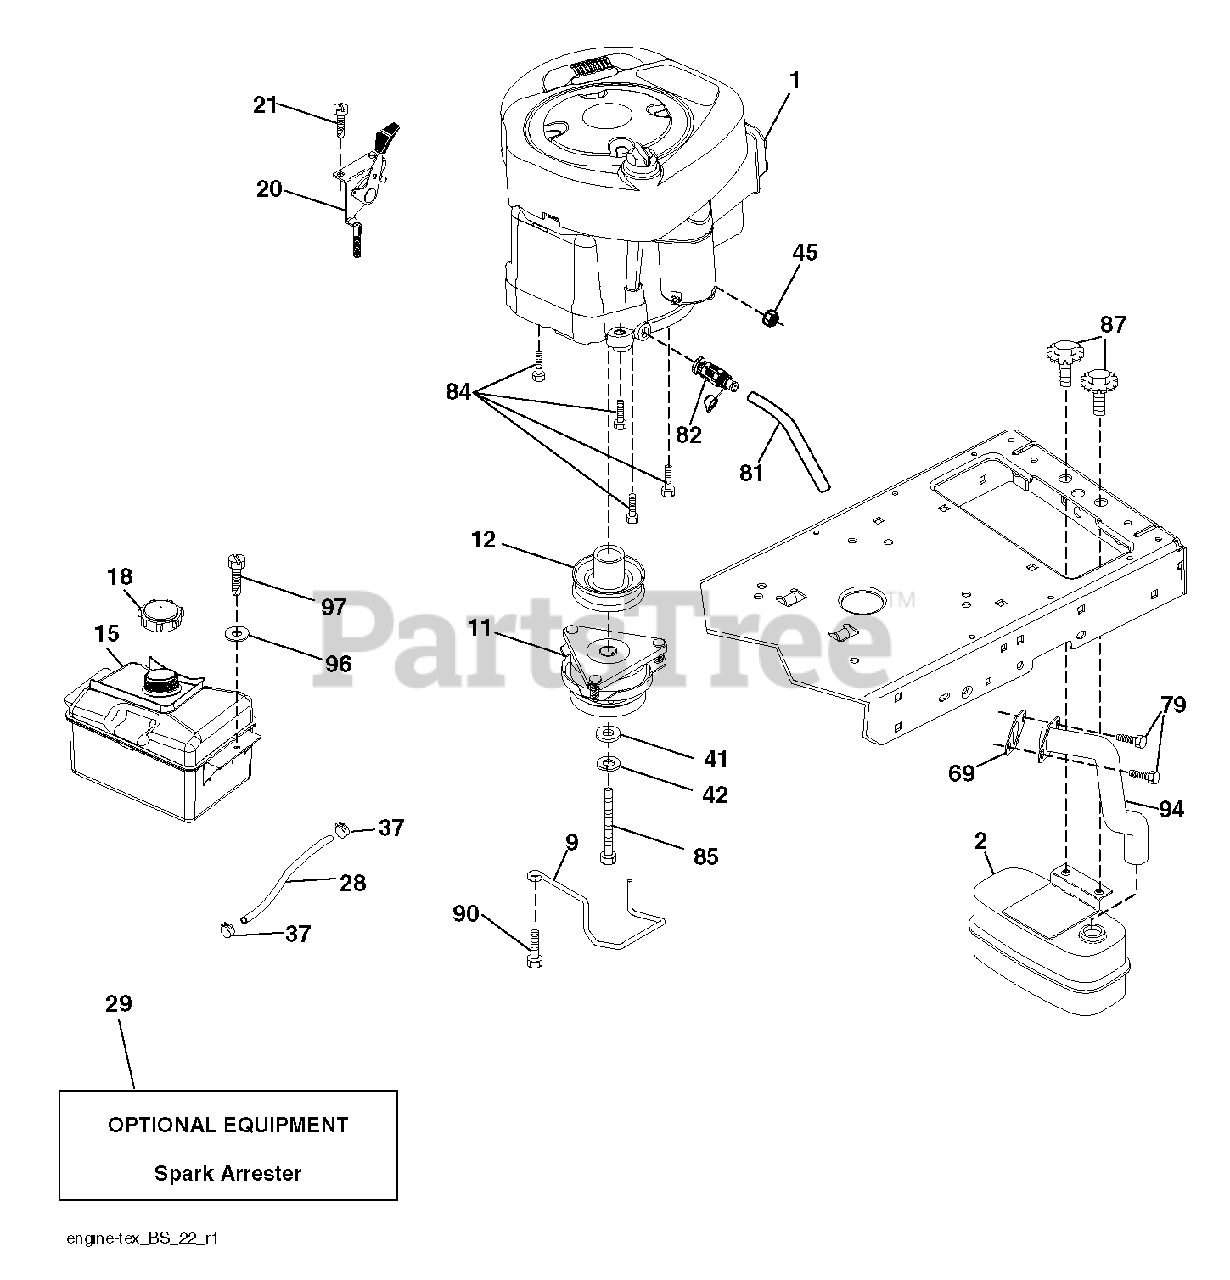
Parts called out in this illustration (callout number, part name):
2	MUFFLER.SINGLE.LRG.BRIGGS.KOHL
9	KEEPER BELT ENGINE
11	CLUTCH.ELECTRIC.LT.48"*
12	PULLEY.ENGINE.TUFFTORQ
15	FUEL.TANK.ASM.NON-EPA
18	CAP ASM.FUEL.2.25"FR.
20	CONTROL.TH/CK.C.
21	SCREW.#10 X 0.750.BOS
28	LINE.FUEL.20
29	KIT.SPARK ARRESTOR 794945 B&S
37	HOSE CLAMP
42	LOCKWASHER
45	NUT
69	REPL BY 532 27 22-93
79	SCREW.SOCKET HD.5/16-1
81	TUBE, DRAIN OIL ASM.
82	VALUE.OIL.DRAIN
84	SCREW.3/8-16
85	BOLT HEX 7/16-20X4-1/4"
87	BOLT, 5/16-18 X 1 3/4
90	SCREW 3/8-16X1
94	EXHAUST.TUBE.B&S.28/31
97	SCREW HEXWSHR 1/4-20X3/4
